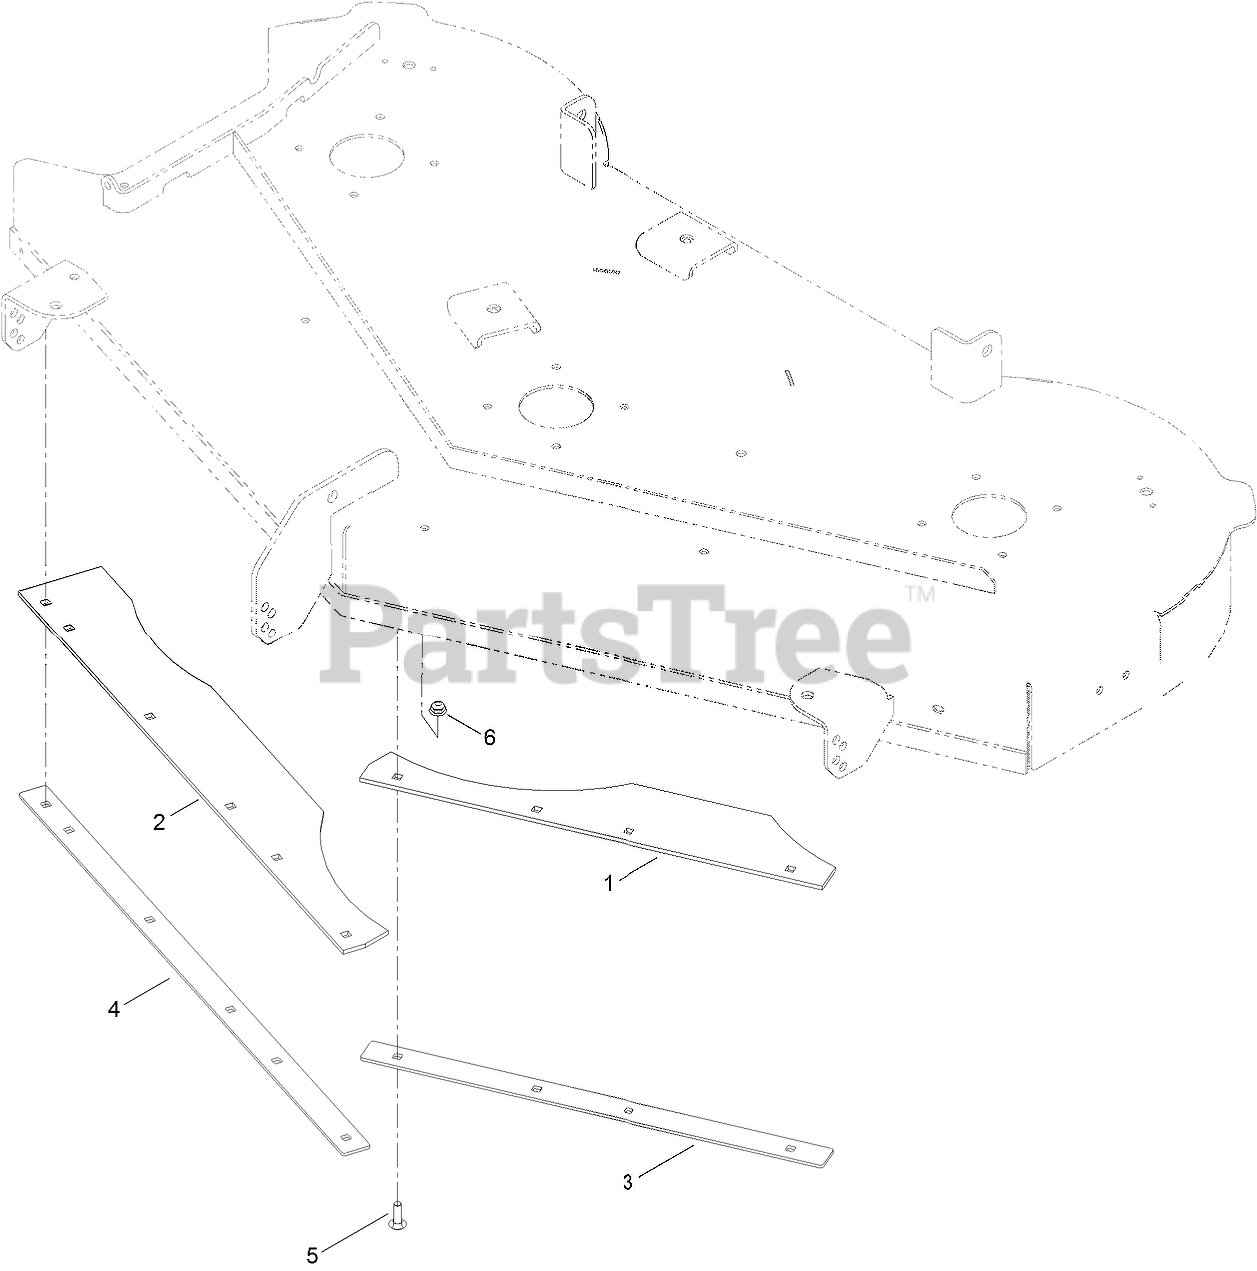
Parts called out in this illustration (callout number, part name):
1	SKIRT-RUBBER, FRONT
2	SKIRT-RUBBER, FRONT
3	PLATE-SKIRT
4	PLATE-SKIRT
5	SCREW-CARR
6	NUT-HF
